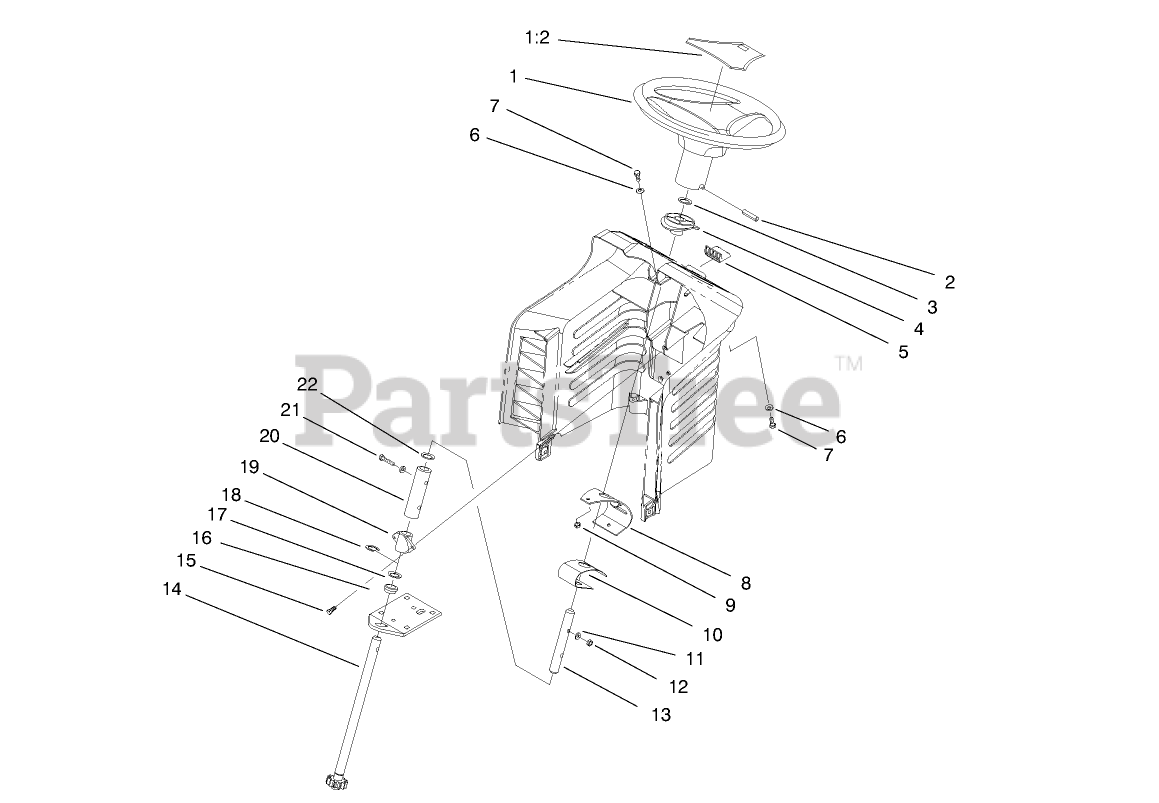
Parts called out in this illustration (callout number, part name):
1:2	COVER-WHEEL
2	PIN-ROLL
3	RING-RETAINING, PUSH, EXT
4	BUSHING-SLIDING
6	WASHER-FLAT
7	SCREW-HH
8	Bracket-Backup
9	NUT-LOCK, NI
10	SPRING LEAF
11	WASHER
12	NUT-LOCK, NI
13	UPPER STEERING SHAFT
14	SHORT STRG SHAFT WA
15	SCREW-SPECIAL
16	BEARING-FLANGE
17	WASHER-THRUST
18	E-RING
19	BUSHING STATIONARY
20	COUPLING, STEERING
21	SCREW-HH
22	WASHER-THRUST
